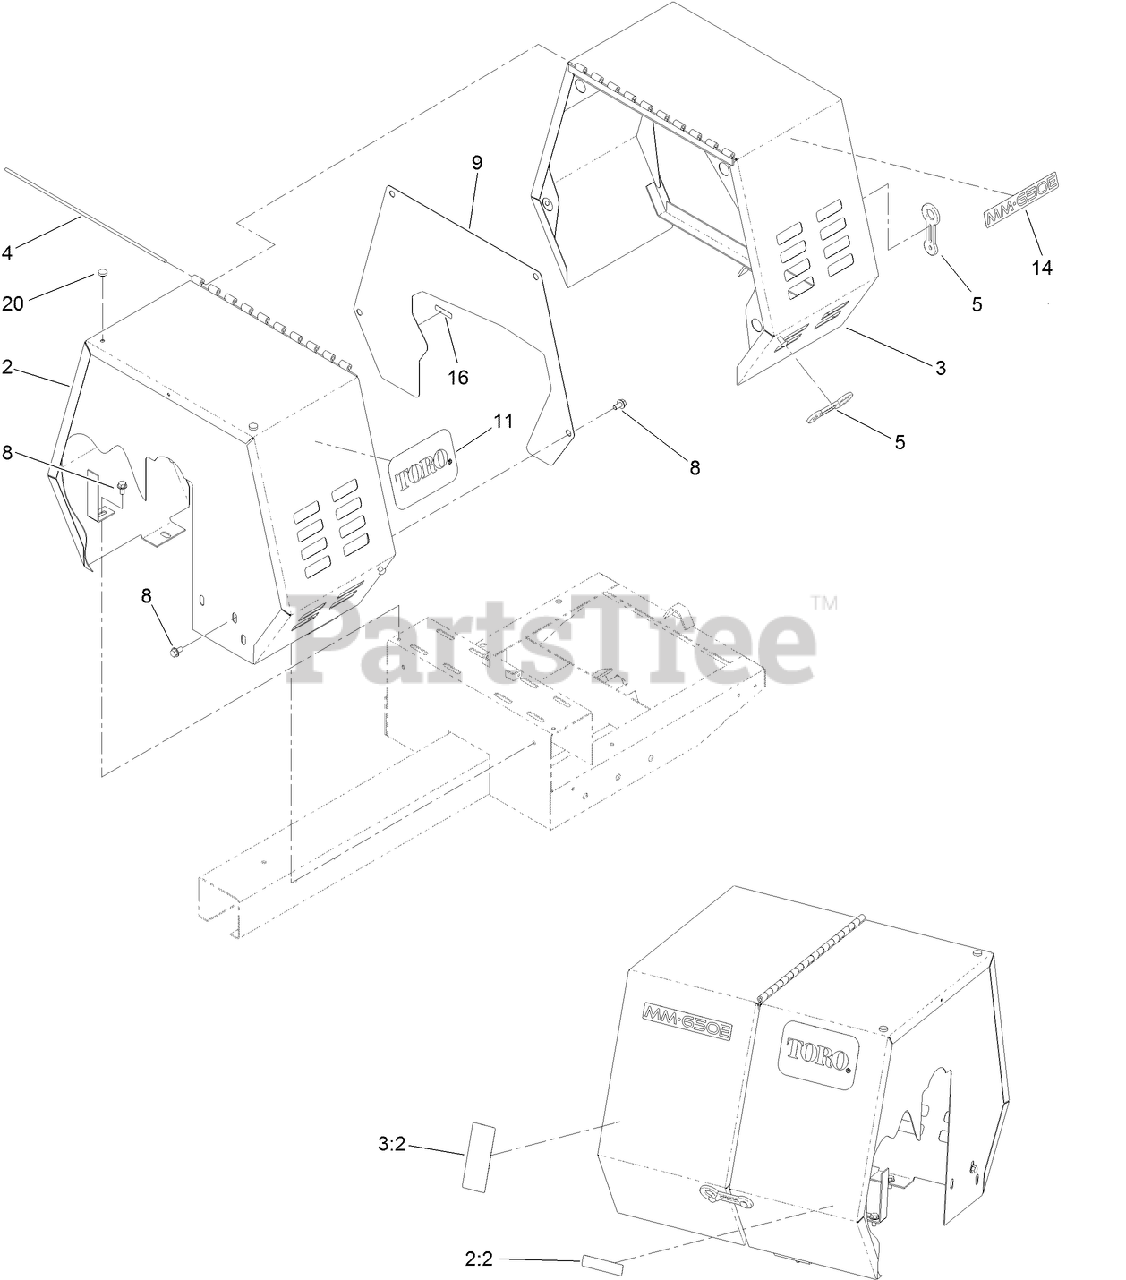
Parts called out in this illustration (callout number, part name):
2	STATIONARY COWL ASM
2:2	DECAL-ARRESTER, SPARK
3	MOVABLE COWL ASM
3:2	DECAL-WARNING
5	LATCH-RUBBER
8	SCREW-HWH
9	PLATE-ACCESS, BELT
11	DECAL
14	DECAL-MM-658H
16	DECAL-GREASE
20	BUMPER
